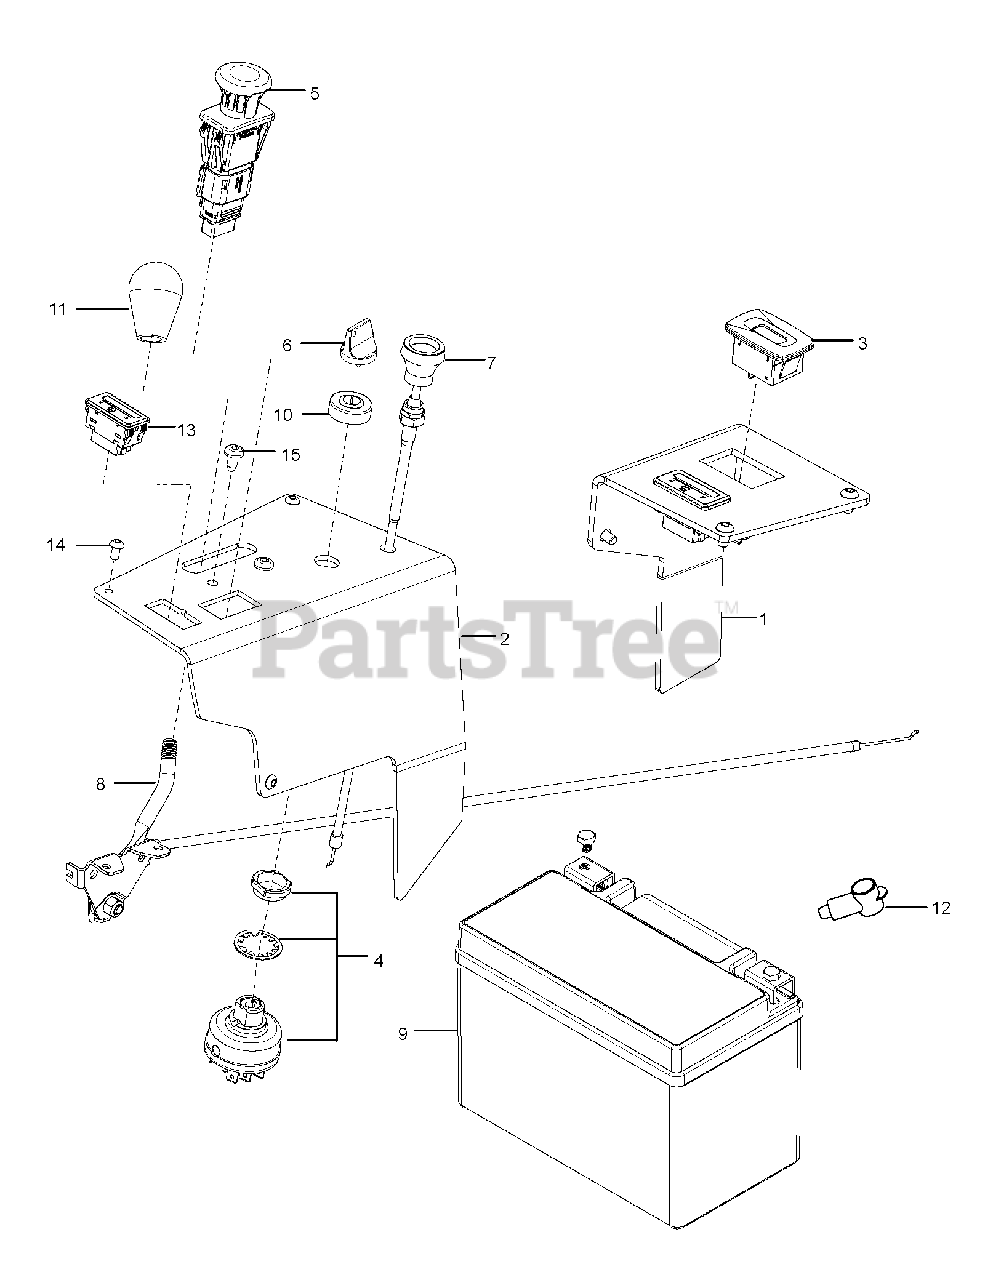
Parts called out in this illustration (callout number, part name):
1	PANEL.LH.CONTROL.PNT.X498
2	PANEL.RH.CONTROL.PNT.X498
3	GUAGE.SRVCMNDR.HRMTR.
4	SWITCH, IGNITION, INDAK
5	SWITCH.PTO.10AMP.SEALED.6P.SPS
6	KEY, IGNITION
7	CABLE, CHOKE, 48"
8	THROTTLE.CONTROL.POST.MZ/PZ.46
9	Starter Battery, 8AH Agm Leoch
10	CAP IGNITION NUT
11	KNOB - SHIFT
13	FUEL GAUGE LED, SMALL FUEL LEV
14	SCR #10-24 X 3/8 SKT HD BLK OX
15	SCREW T-30 1/4-20 X
